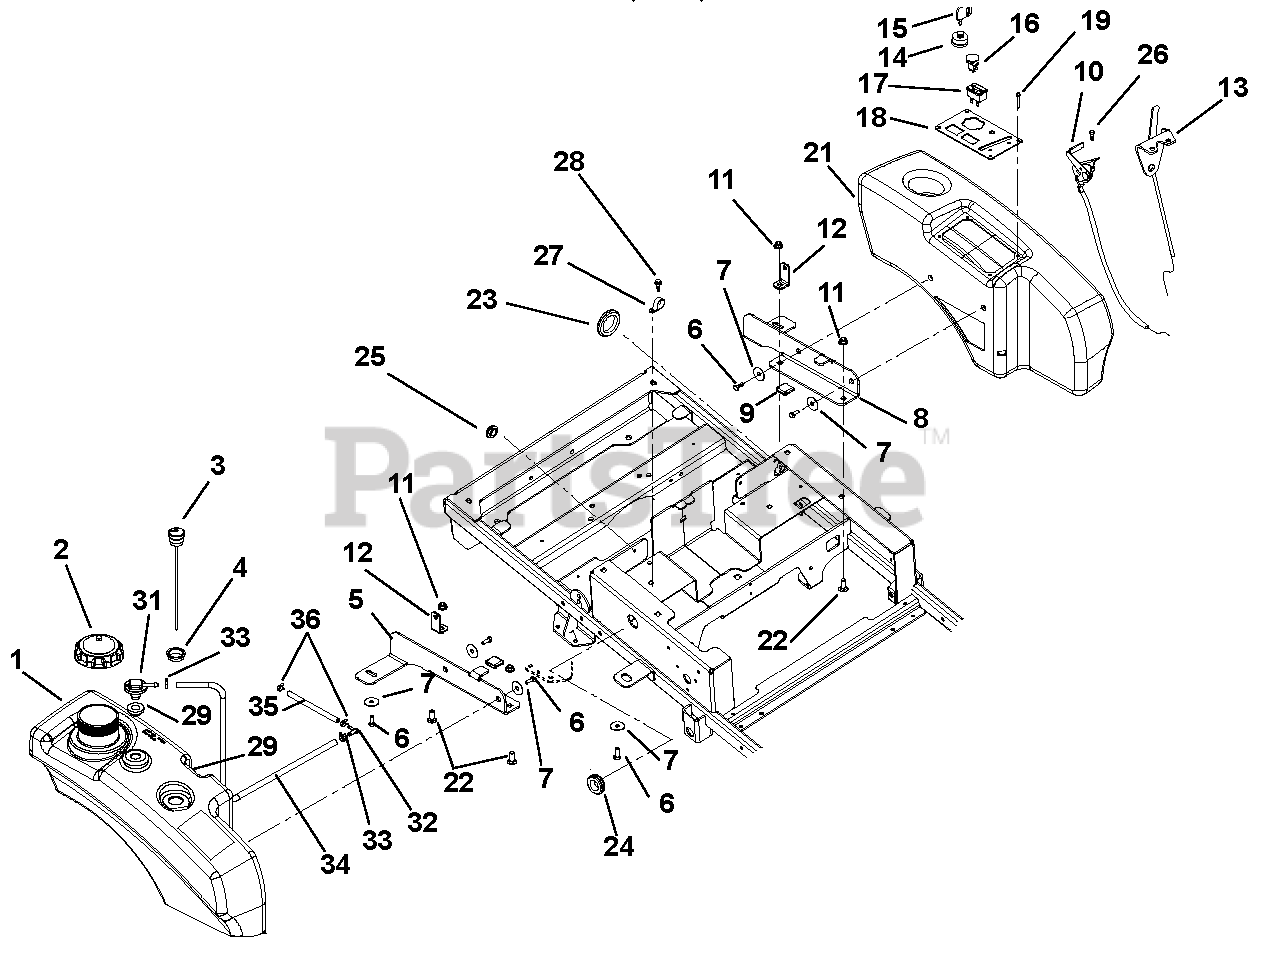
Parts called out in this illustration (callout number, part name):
1	Tank, XL Non-Permeable Fuel
2	Cap, 3.50" Vent-in Ratchet
3	Gauge, Remote Fuel 10.0"
4	Grommet, Fuel Gauge
5	Bracket, Right Hand Rear Tank Mount
6	Bolt, Serrated Hex Flange Washer Head .312-18 x .50
7	Washer, Flat Steel .347 x 1.254 x .048
8	Bracket, Left Hand Rear Tank Mount
9	Grip, Rubber
10	Cable, Throttle
11	Nut, .38-16 Nyloc Flange
12	Bracket, Hood Pivot
13	Cable, Choke
14	Key Switch
15	Key, w/Cap
16	Switch, Clutch
17	Hour Meter, Digital
18	Panel, Control
19	Screw, Hex .25 x 14-.75
20	Fender, XL
21	Bolt, Round Head Square Neck .38-16 x 1.00 Grade 5
22	Grommet, 2.00"
23	Grommet .125 x 1.000 ID
24	Grommet, Rubber 5/8 ID/1.13 OD
25	Screw, Tapping 10-24 x .50 Hex Washer Head Thread
26	Clamp, Cushioned Steel
27	Screw, Tap Hex Washer Head .38-16 x .5
28	Tube, Fuel Pick-up (XL)
29	Grommet, Remote Vent, Nitrile
30	Vent, Roll-over (.25" ID hose)
31	Fitting, 3/16 x 1/4 90 Degree VAC
32	Clamp, Fuel Line
33	Hose, .25 Low-Perm Bulk Gas
34	Hose, .188 Low-Perm Bulk Gas
35	Clamp, Hose, Spring .188
